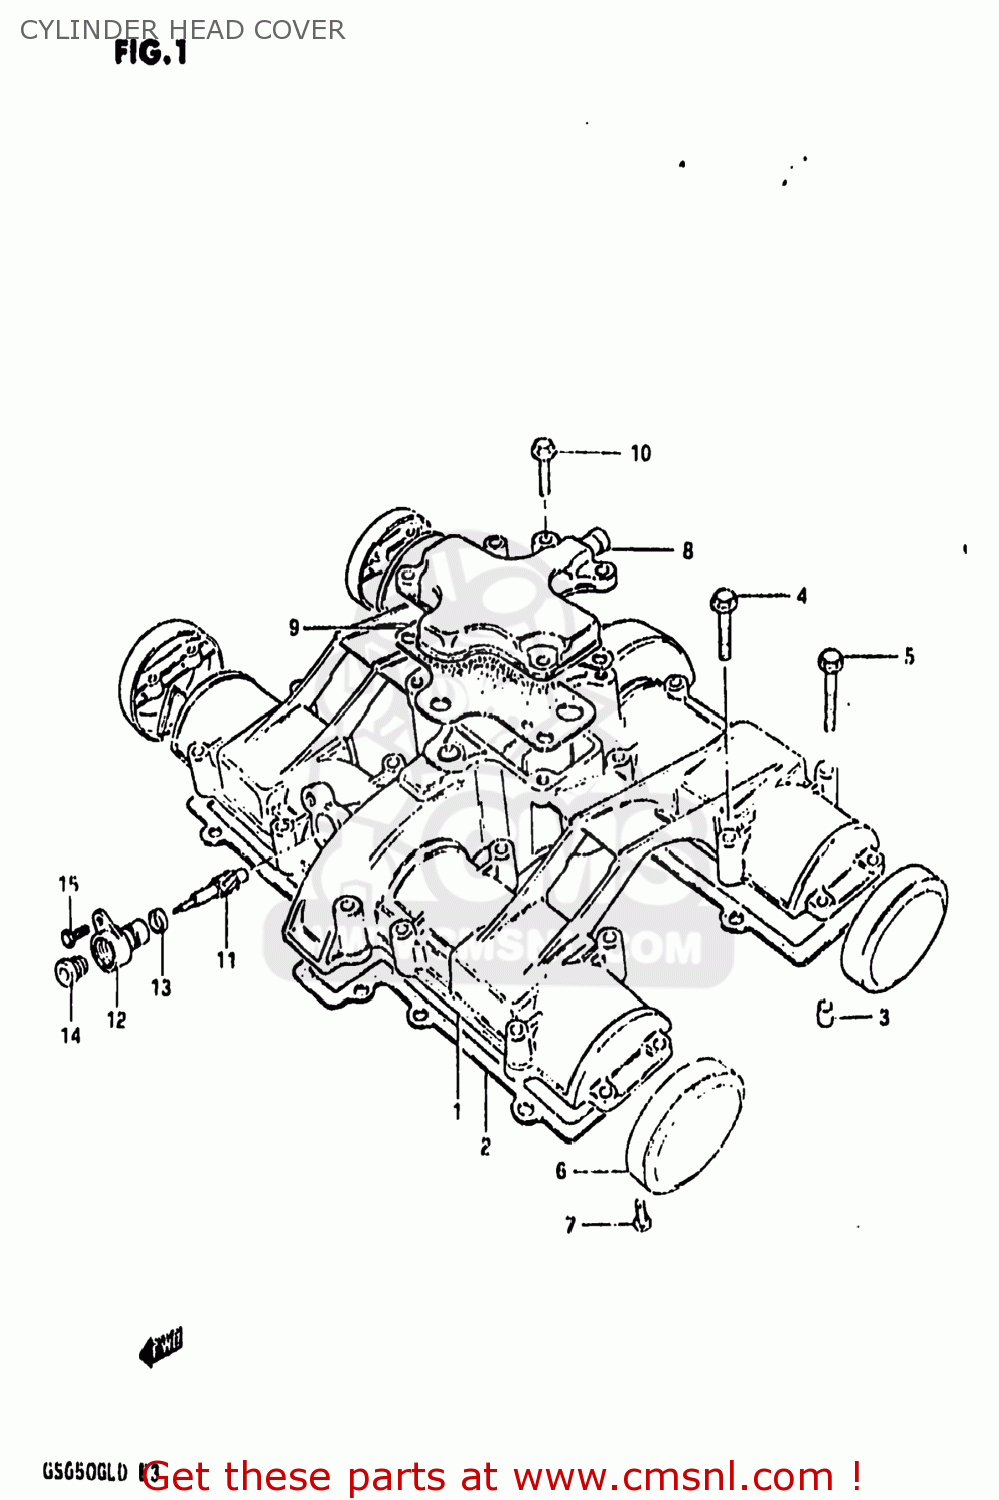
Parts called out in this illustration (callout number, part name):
1	COVER,CYLINDER HEAD
2	GASKET,CYLINDER HEAD COVER (MCA)
3	PIN
4	BOLT (6X40)
5	BOLT (6X45)
6	CAP,CYLINDER HEAD COVER
7	SCREW
8	COVER,BREATHER
9	GASKET (MCA)
10	BOLT
11	GEAR,TACHOMETER DRIVEN
12	SLEEVE,TACHOMETER DRIVE GEAR
13	SEAL,TACHOMETER DRIVEN
14	SEAL,OIL(5X12X8)
15	SCREW(5X12)
